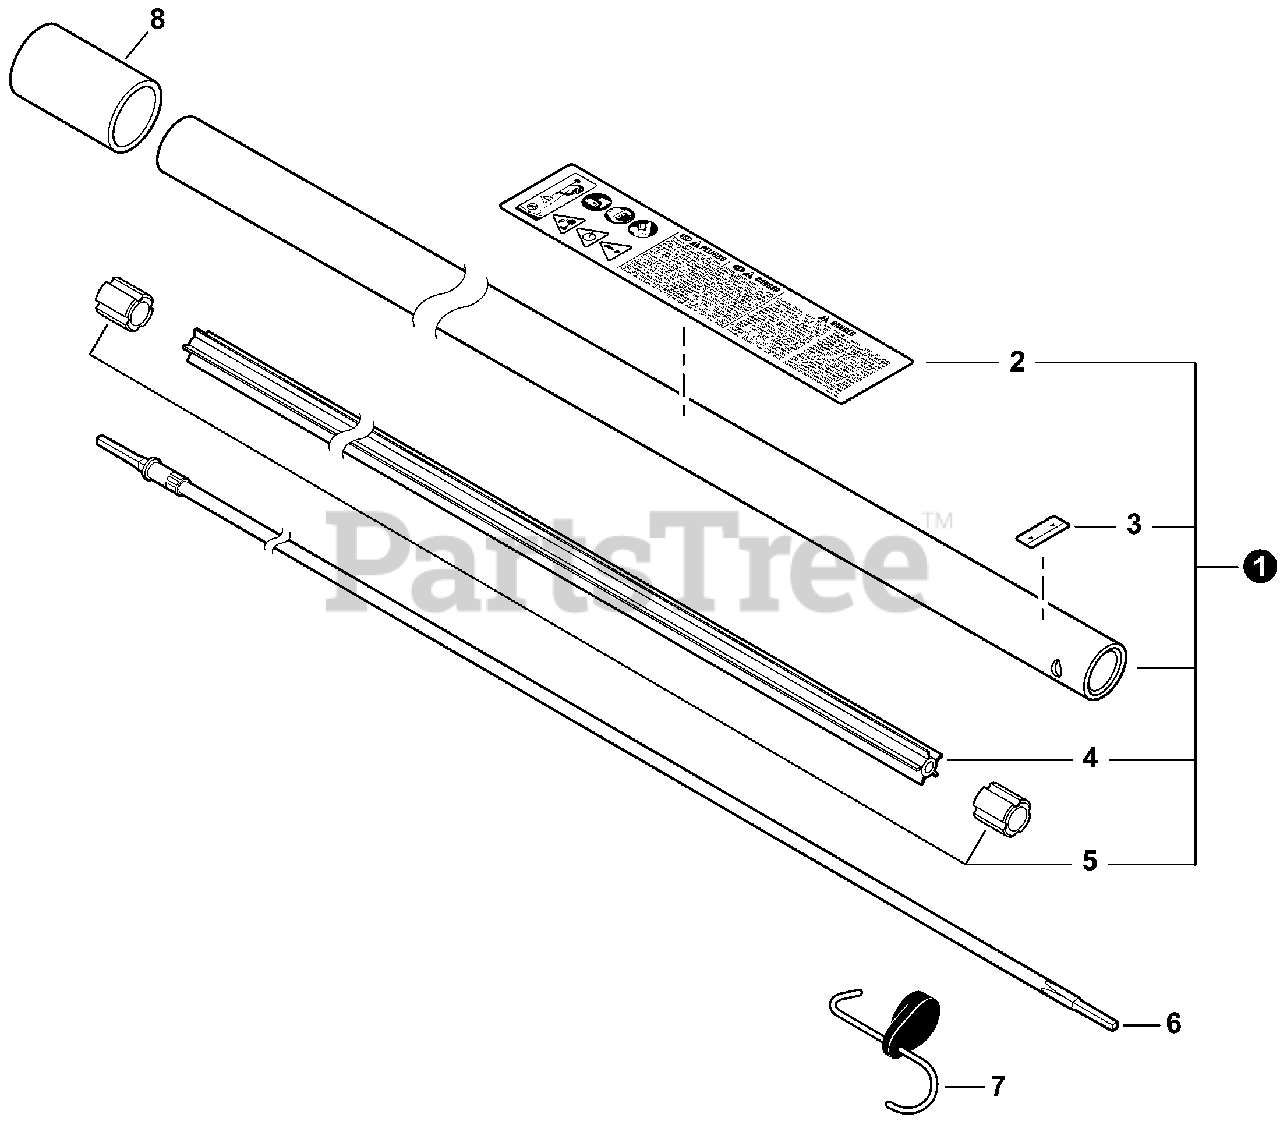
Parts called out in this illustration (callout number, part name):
1	MAIN PIPE ASSY
2	LABEL, CAUTION
3	LABEL - ALIGNMENT
4	LINER - FLEXIBLE
6	DRIVESHAFT - FLEXIBLE
7	HANGER, ATTACHMENT
8	PROTECTOR, MAIN PIPE 25 MM
